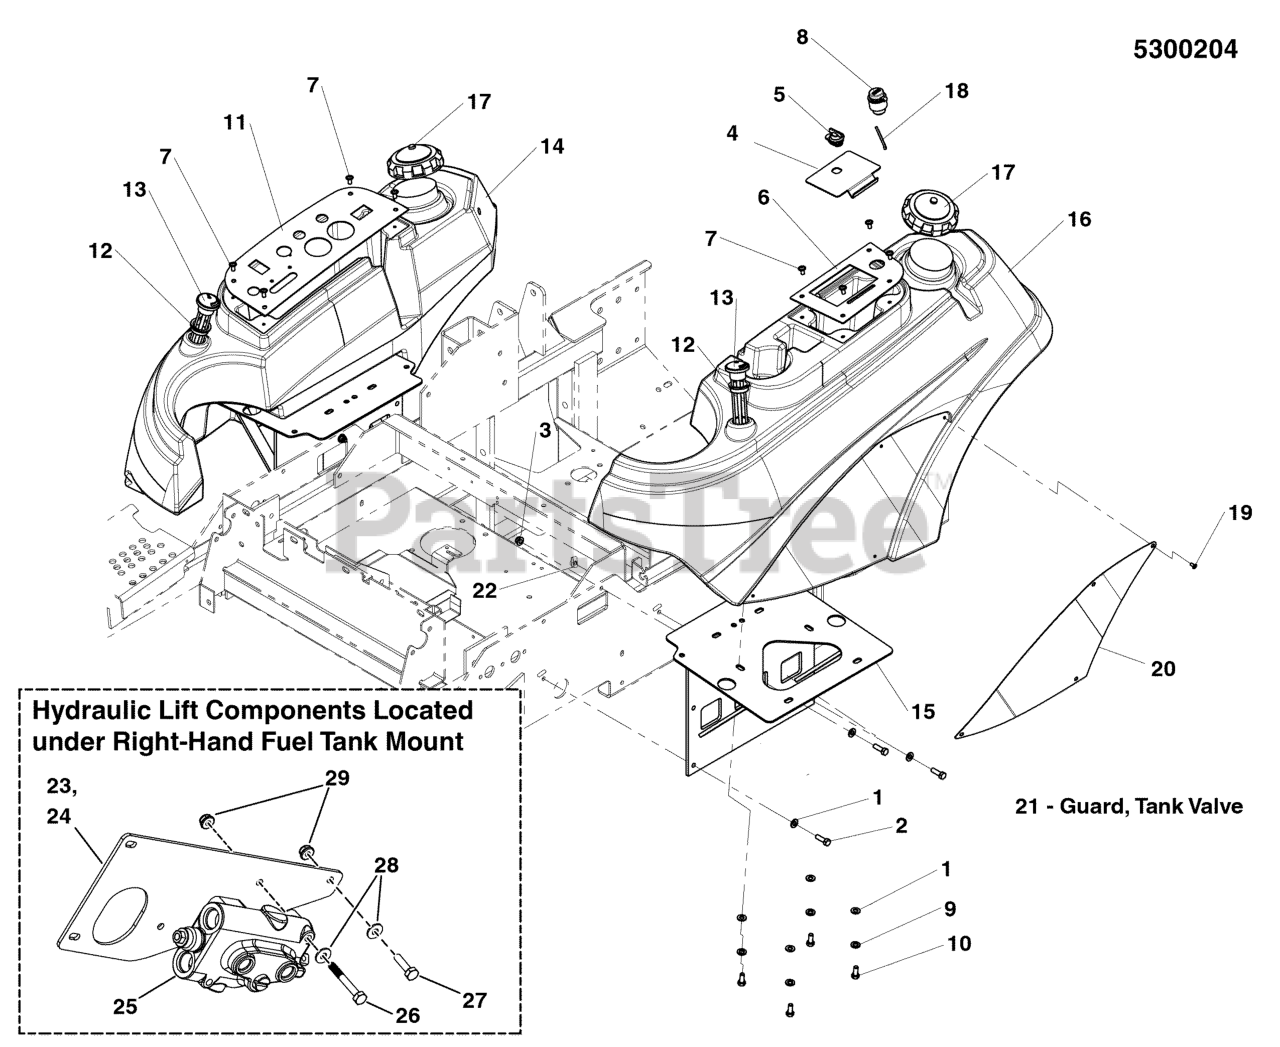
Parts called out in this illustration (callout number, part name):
1	WASHER, 5/16" SAE
2	BOLT, 5/16-18 X 1" GD5
3	NUT, 5/16-18 HEX NYLOCK FLANGE
4	COVER, CONTROL PANEL
5	LATCH, CONTROL PANEL
6	PANEL, CONTROL - LH
7	SCREW, ALLEN HEAD, 1/4-20X1/2
8	POWER, OUTLET - 12 VOLT
9	WASHER, 5/16 LOCK CZ
10	BOLT, 5/16-18 X 3/4 GD5
11	CONTROL PANEL
12	GROMMET, FUEL GAUGE
13	GAUGE, FUEL, 12
14	TANK, FUEL, DIESEL, RH
15	WELD, FUEL TANK MOUNT
16	TANK, FUEL, DIESEL, LH
17	FUEL CAP, 3.5", NON VENTED, DIESEL (GRN)
18	PIN, COTTER, 1/8 X 1-1/4
19	SCREW, Allen Head, #10-24 x 3/8"
20	PLATE, BADGE, IS4500Z
22	BODY CLIP, 5/16-18-7GA MATERIAL
23	BAR, SOLENOID MOUNT - RED
24	PLATE, VALVE MOUNT, IS5100Z - RED
25	HYDRAULIC VALVE
26	BOLT, 1/4-20 X 2", GD5
27	BOLT, 1/4-20 X 1" GD5 CZ
28	WASHER, 1/4 SAE
29	NUT, 1/4-20 HEX NYLOCK FLANGE
